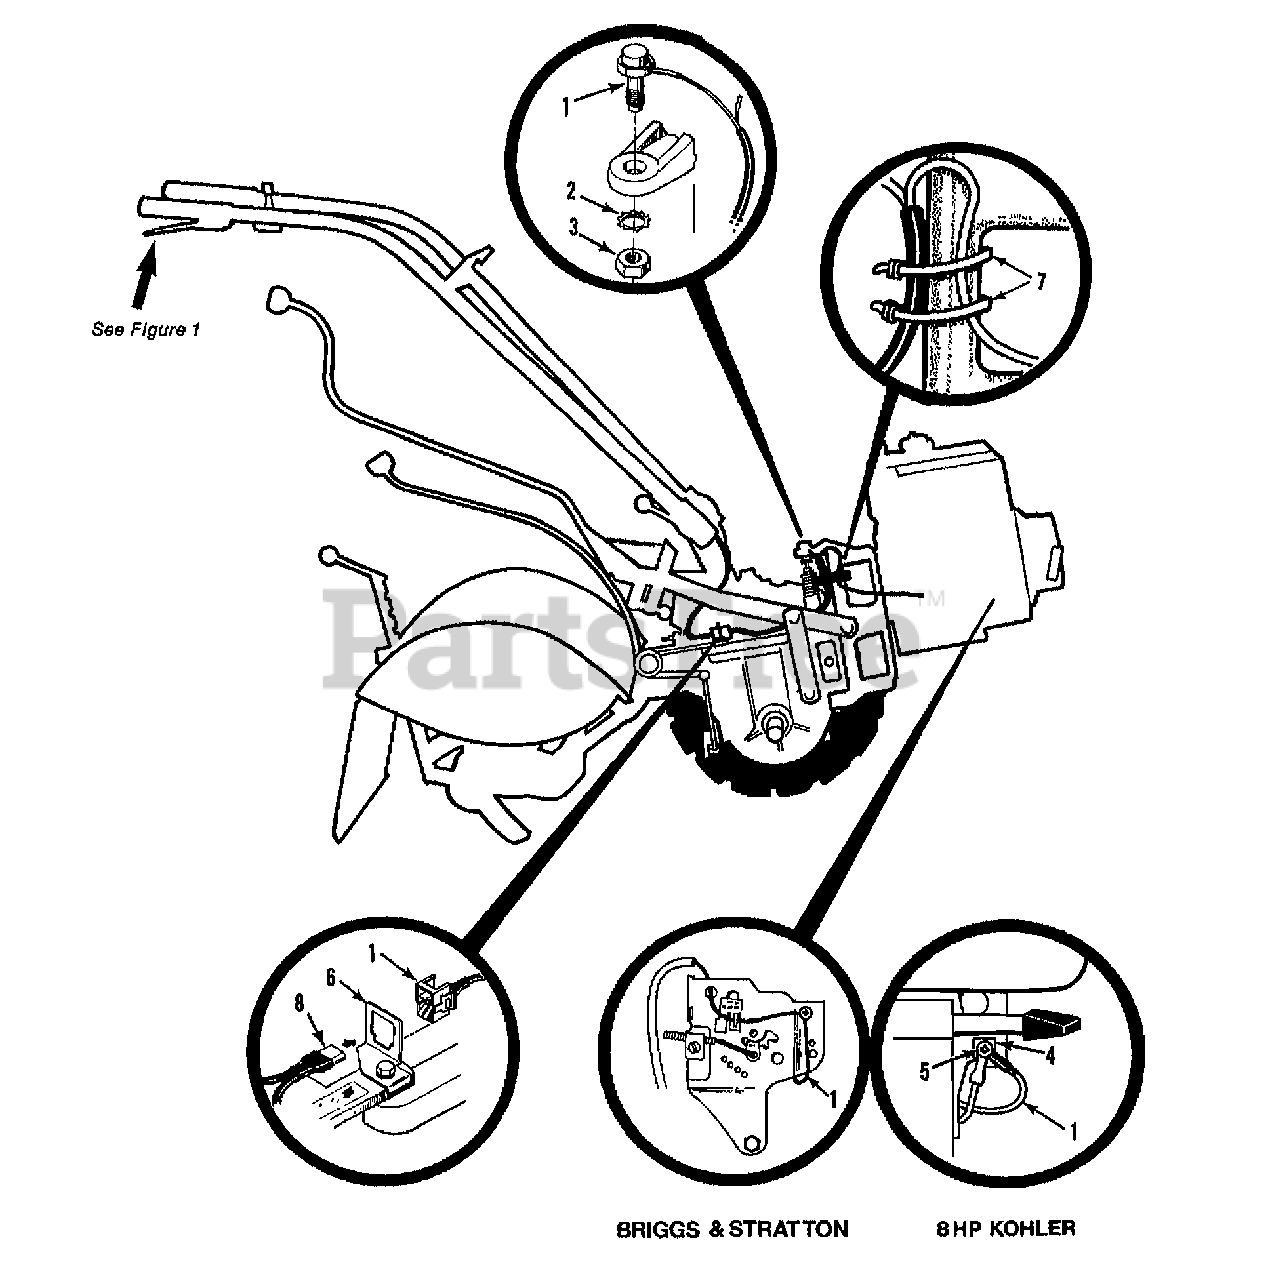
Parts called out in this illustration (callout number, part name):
1	HARNESS-WIRE ENG OPC
2	WASHER-LK .438 EXT TOOTH
3	NUT-HEX/JAM 7/16-20
4	GROMMET-7 T/L & 8 KOH OPC
5	SCR #8-18 SELF TAP
6	CLIP-CONNECTOR
7	TIE-RED
8	HARNESS-WIRE OPC HORSE
